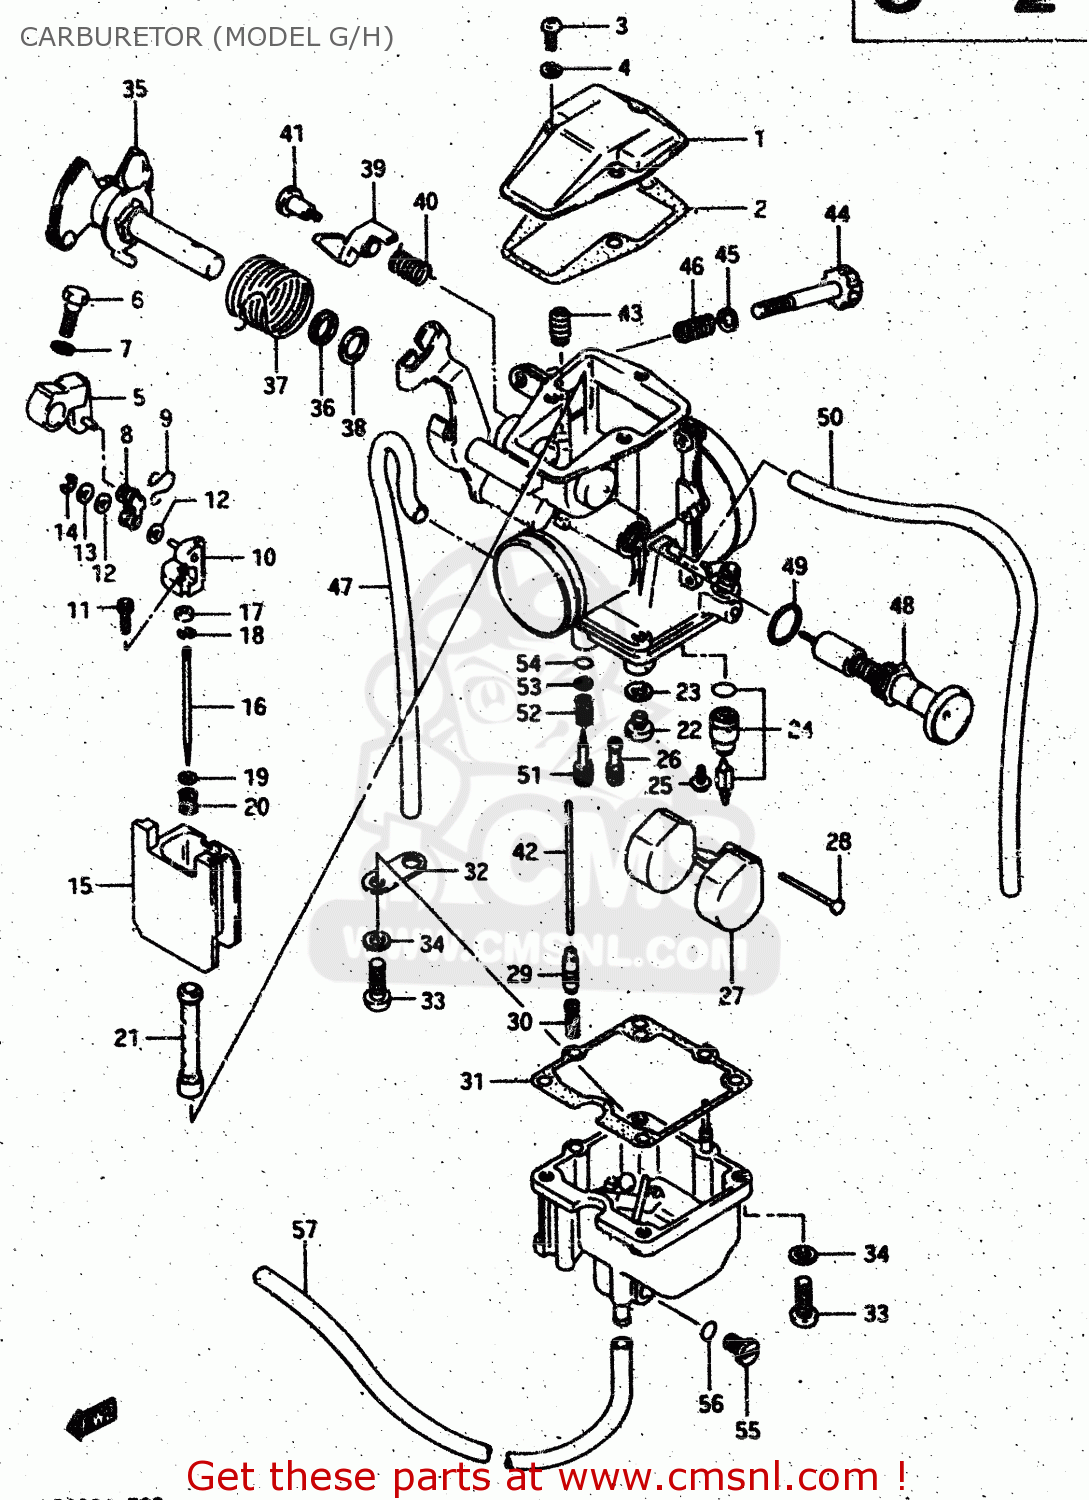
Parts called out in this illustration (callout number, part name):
1	CAP, TOP
2	GASKET,CARBURETOR TOP (NAS)
3	SCREWM4X0.7X10
4	LOCK WASHER
5	ARM,THROTTLE
6	BOLT
7	LOCK WASHER
8	PLATE
9	SPRING
10	BRACKET
11	SCREW
12	GASKET (NAS)
13	WASHER
14	E-RING
15	VALVE,THROTTLE
16	NEEDLE,JET
17	RING
18	CLIP
19	WASHER,JET NEEDLE
20	SPRING
21	JET,NEEDLE(O-0)
22	JET,MAIN(135)
23	WASHER,NEEDLE NOZZLE
24	VALVE ASSY,NEE
25	SCREW
26	JET,PILOT(15)
27	FLOAT
28	PIN,FLOAT
29	PLUNGER
30	SPRING
31	GASKET,FLOAT CHAMBER (NAS)
32	PLATE
33	SCREW
34	LOCK WASHER
35	SHAFT ASSY
36	SEAL
37	SPRING
38	RING,THROTTLE SHAFT
39	LEVER
40	SPRING
41	BOLT
42	ROD,PLUNGER
43	BOOT, ACCELE PUMP ROD
44	SCREW,THROTTLE STOP
45	WASHER
46	SPRING
47	HOSE (3.5X6.5X200)
48	PLANGER ASSY
49	O RING
50	HOSE
51	SCREW,PILOT
52	SPRING
53	WASHER
54	O RING,PILOT AIR SCREW
55	PLUG
56	GASKET,DRAIN,PLUG (NAS)
57	HOSE
